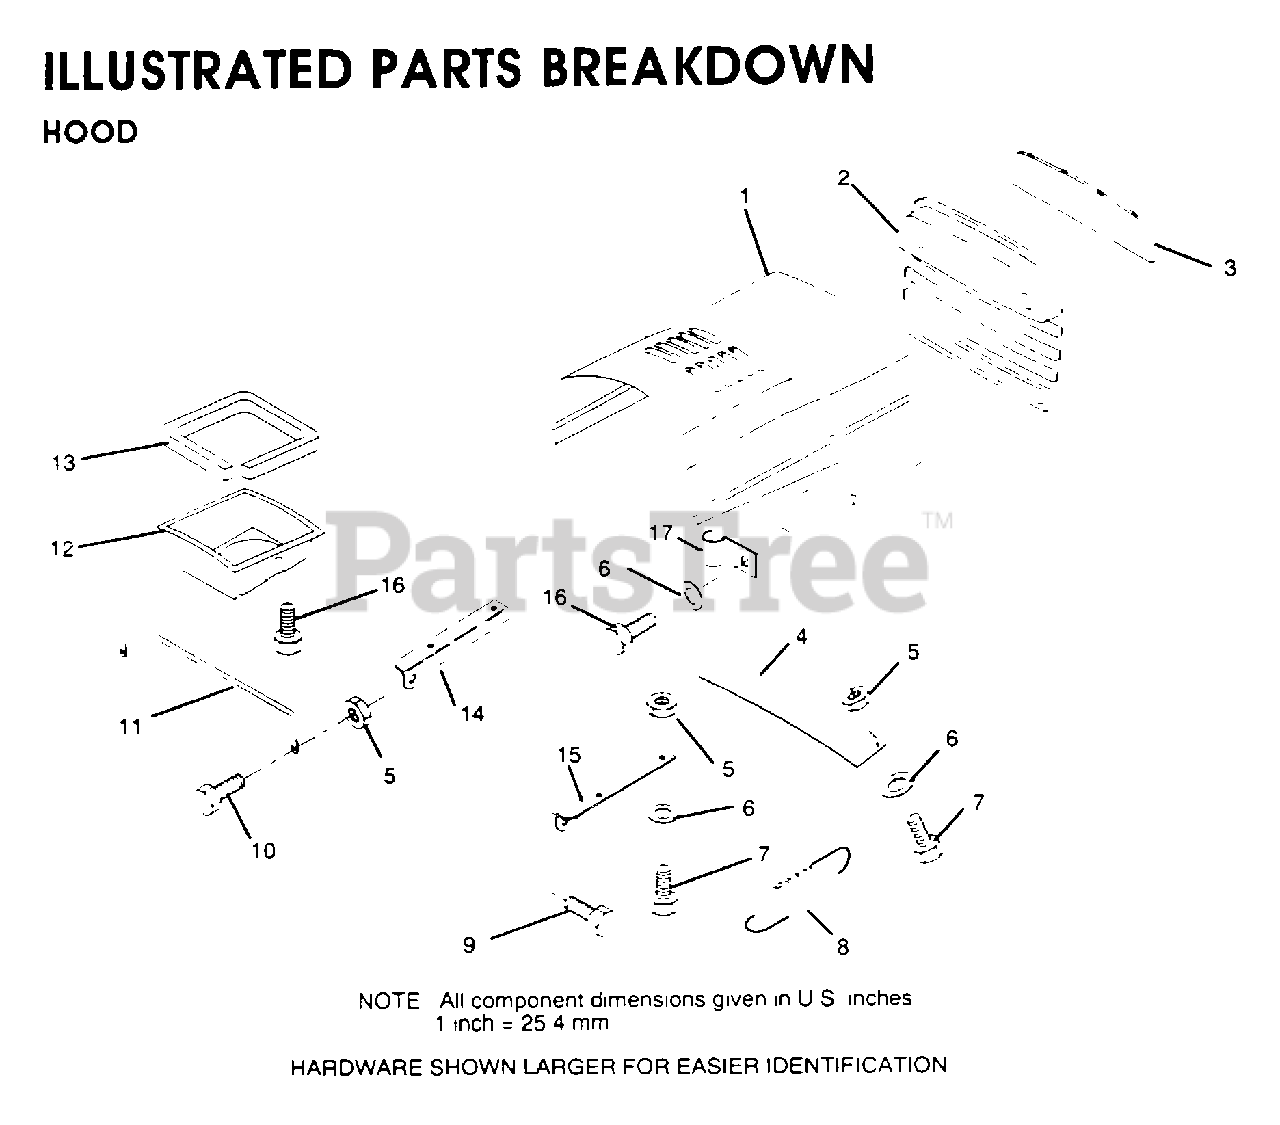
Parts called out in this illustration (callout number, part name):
2	GRILL
3	LENS
4	"STRAP,GRILL T"
5	NUT
6	WASHER
7	BOLT
8	EXT SPRING
11	"BRACE,HOOD"
12	"DUCT,AIR"
13	FOAM STRIP LT
14	BRKT HOOD LH
15	BRKT HOOD RH
17	CLIP T
